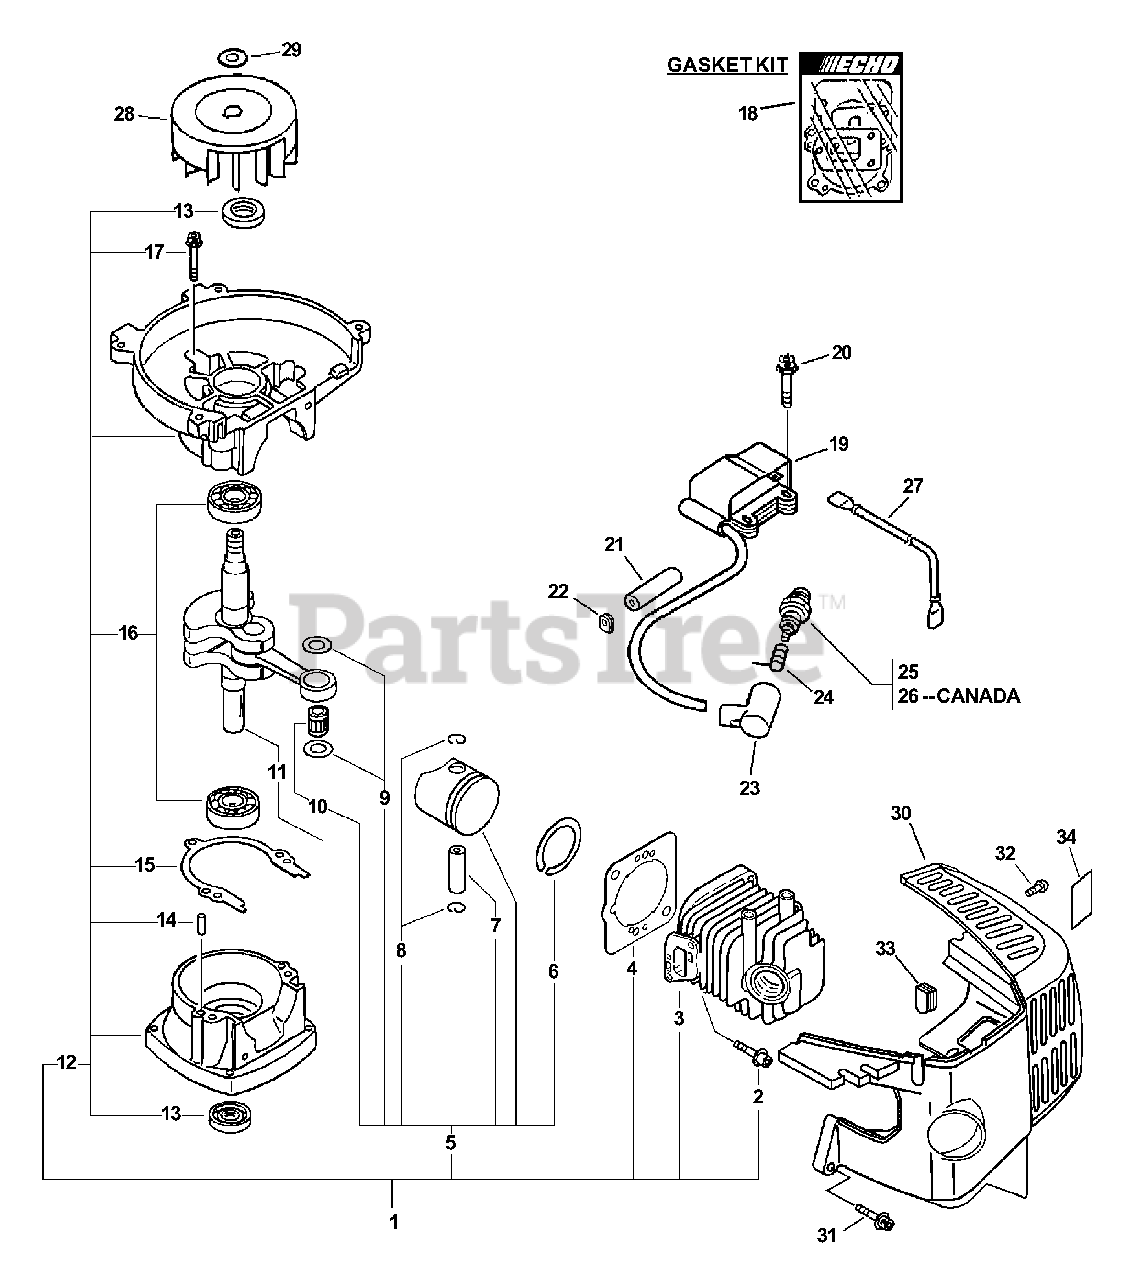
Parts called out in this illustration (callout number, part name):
1	SHORT BLOCK -- SB1075
2	SCREW - 4X22
3	CYLINDER
4	GASKET, CYLINDER
5	PISTON KIT
6	RING, PISTON
7	PIN, PISTON
8	RING, RETAINING
10	BEARING, NEEDLE - 8
11	CRANKSHAFT ASSY
12	CRANKCASE KIT
13	SEAL, OIL
14	PIN - LOCATING
15	GASKET, CRANKCASE
16	BEARING, BALL - 6201
17	SCREW - 5X28
18	GASKET KIT
19	COIL, IGNITION
20	SCREW - 4X20
21	TUBE, INSULATOR
23	CAP, SPARK PLUG
24	TERMINAL, SPARK PLUG CAP
25	SPARK PLUG -- BPM-8Y
26	SPARK PLUG -- BPMR-8Y
27	LEAD - IGNITION
28	FLYWHEEL
29	WASHER - 8
30	COVER, ENGINE
31	SCREW - 5X22
32	SCREW - 4X8
33	PLUG
34	LABEL - HOT SURFACE
